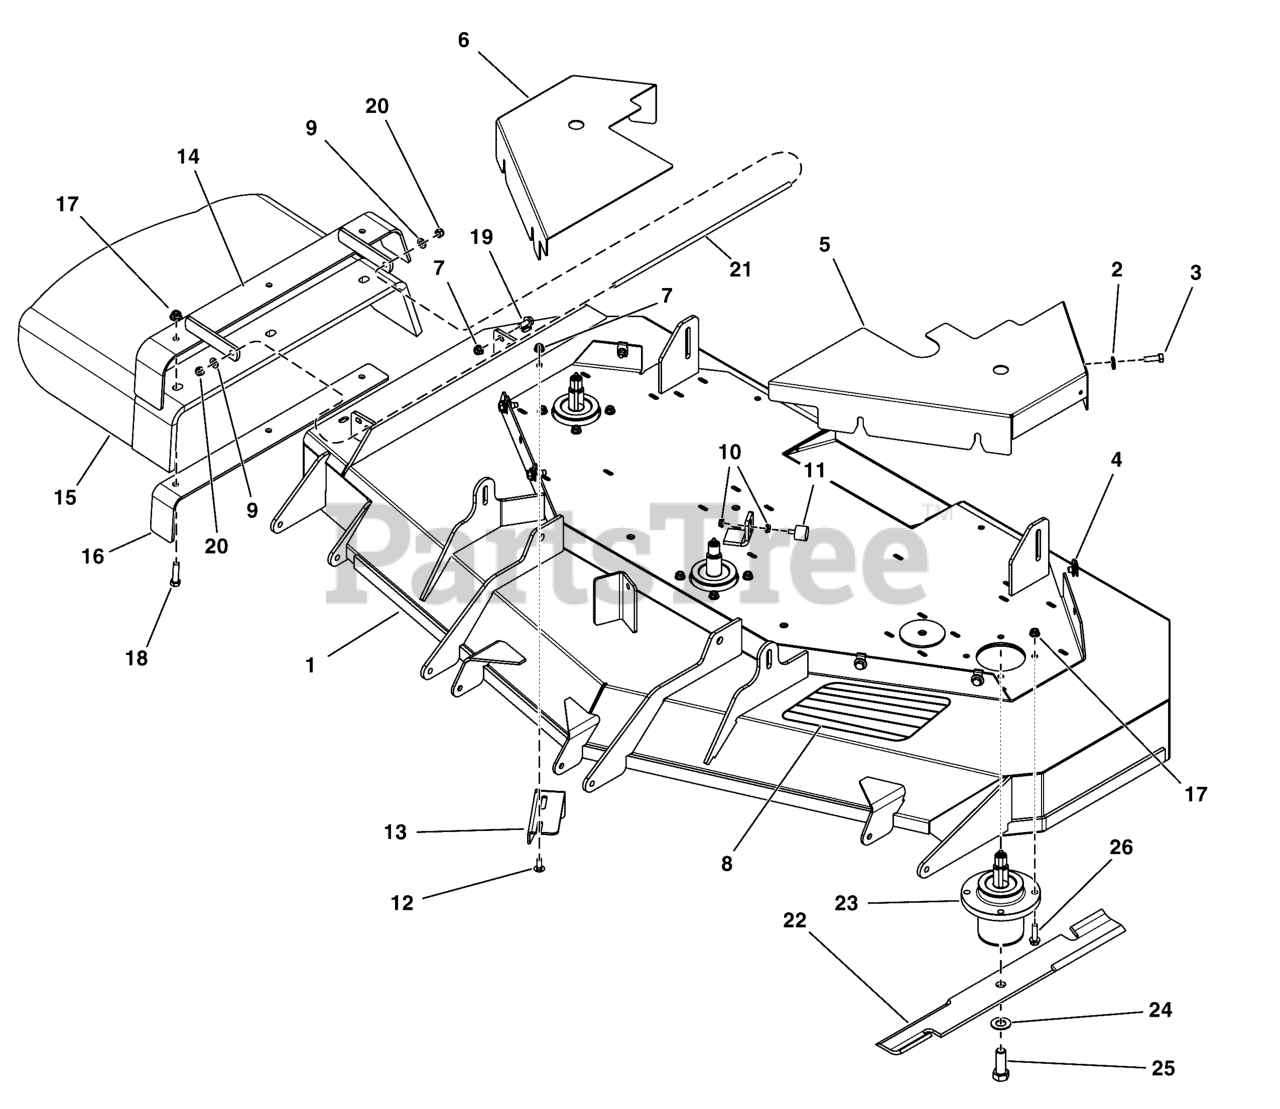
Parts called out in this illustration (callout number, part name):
1	DECK SHELL W/ DECALS, CNTDR XT-61
2	WASHER, Flat, 5/16
3	CAPSCREW, Hex Head, 5/16-18 x 1
4	CLIP, BODY , 5/16-18 FOR 7 GA.
5	GUARD 61" LH - ORG
6	PLATE, GUARD, 61, RH - ORG
7	NUT, Flange Nylock, 5/16-18
8	SAFETY WALK, 4.00 X 7.50
9	WASHER, Flat, 5/16
10	NUT, Serrated, Flange, 1/4-20, GR5
11	BUMPER, RUBBER, 1/4-20 X 7/8" STUD
12	BOLT, 5/16-18 X 3/4, CARRIAGE, GD5, CZ
13	PLATE, Deflector
14	WELD, MOUNT, DISCHARGE CHUTE - BLK
15	CHUTE, RUBBER DISCHARGE (5104442)
16	SUPPORT, DISCHARGE CHUTE - BLK
17	NUT, Hex Flange, Nylock, 3/8-16
18	BOLT, Carriage, 3/8-16 X 1 1/2, GR5
19	SCREW, Flange, Whiz-Lock, 5/16-18 X 3/4
20	NUT, Hex Lock, Nylon, 5/16-24
21	MOUNT, Chute
22	BLADE 21 X .25 X 2.5
23	SPINDLE ASSEMBLY, Complete (See Spindle Service Parts group)
24	WASHER, Blade Bolt, 9/16"
25	BOLT, 5/8-11 X 1 3/4, GR 8
26	BOLT, Flange, 3/8-16 X 1 1/4
